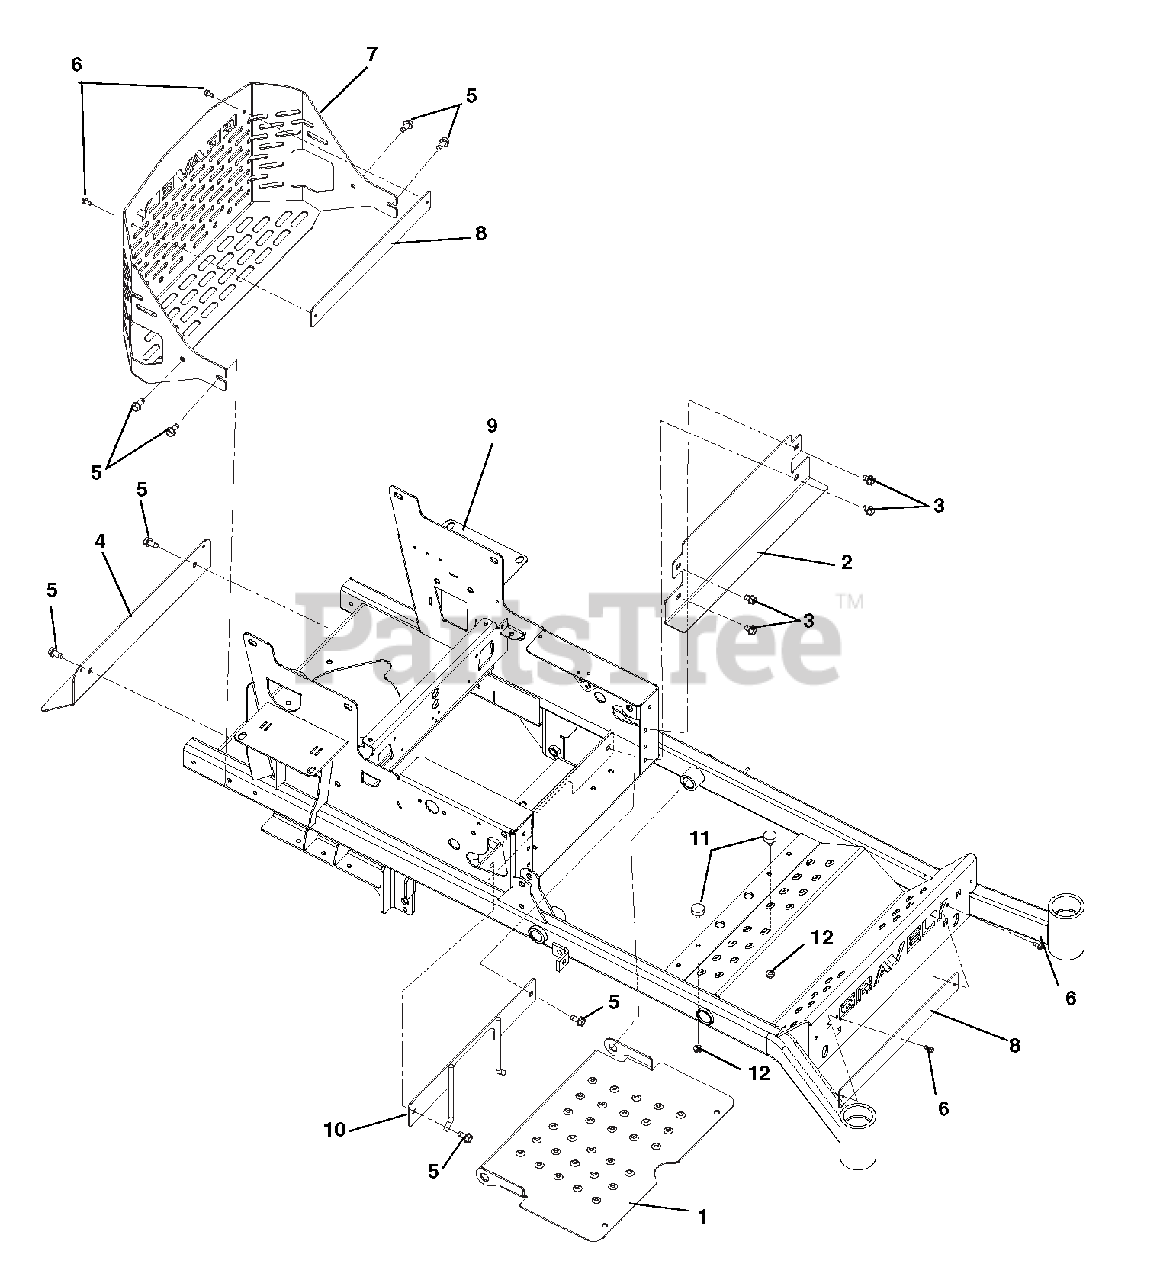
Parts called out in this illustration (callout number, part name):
1	100I FOOT PLATE - RED
2	100I KICK PLATE - RED
3	@SCR-TAP .38-16X.50 HWH TR YWZ
4	MUFFLER HEAT SHIELD - BLACK
5	@SCR-TAP .38-16X.75 HWH TR YWZ
6	SCR-TAP .25-20X.50 HWH TR YWZ
7	PRO-TURN 100 BUMPER - RED
8	BUMPER PLATE 2.00 X 16.50 -BLK
9	PT100 60" MAIN FRAME WMT - RED
10	PTO BELT FINGER WLDMT - BLK
11	BUMPER, RUBBER
12	@NUT-SPNLK-FLG .312-18 YWZC
